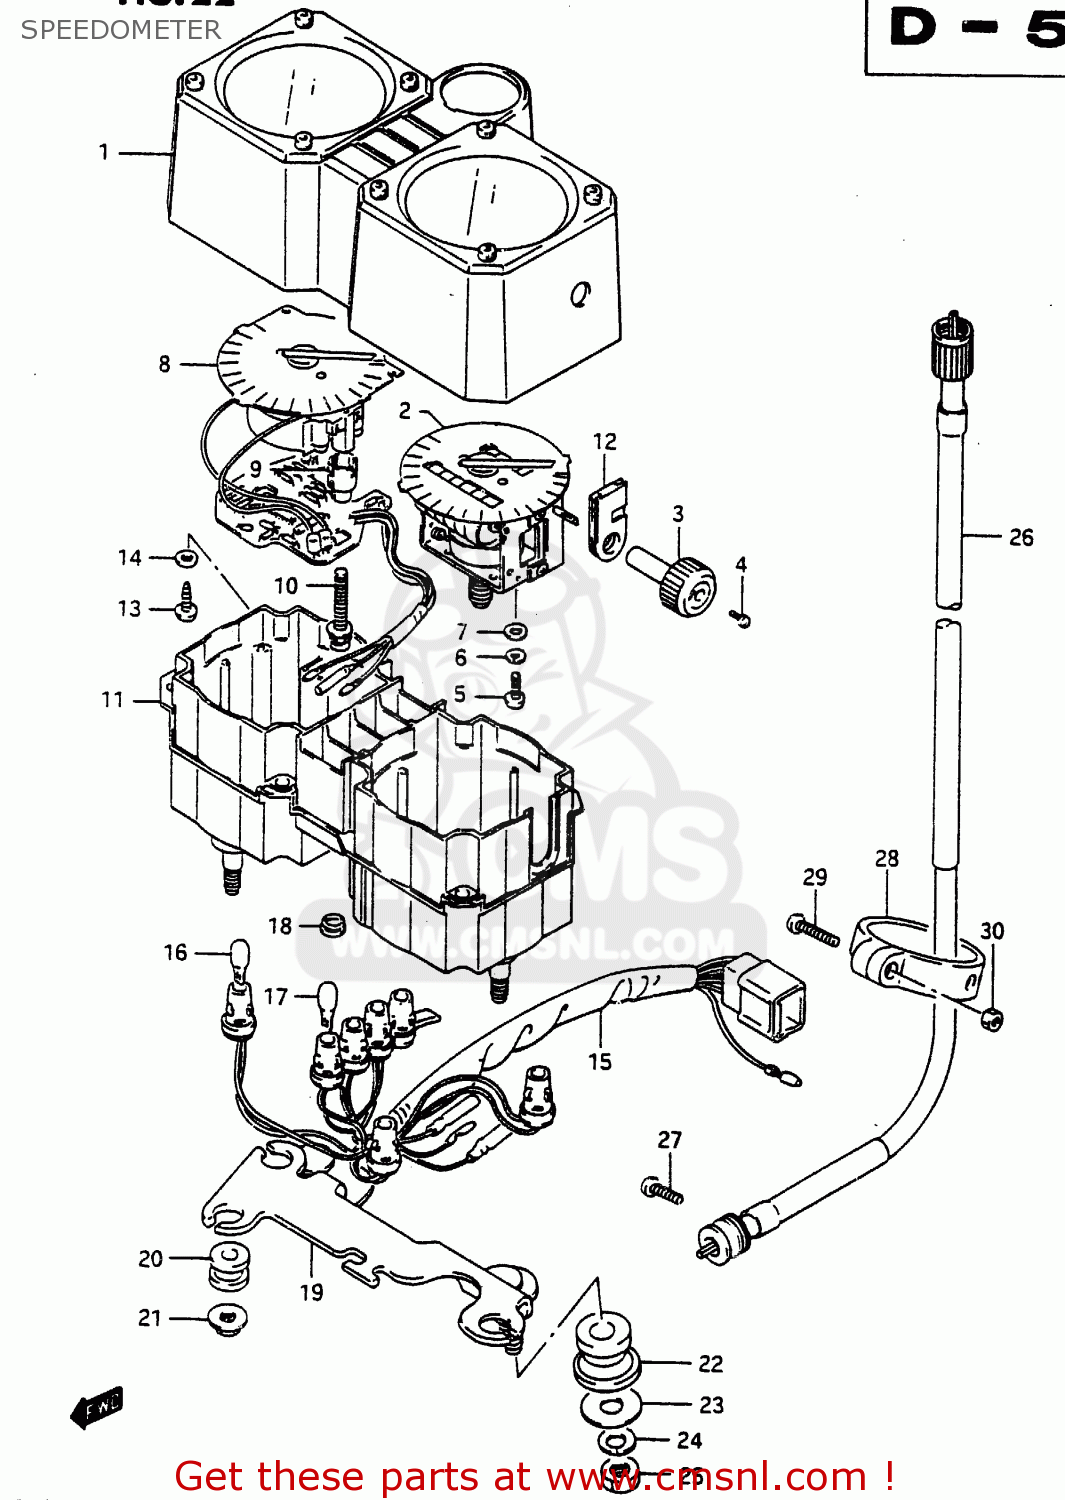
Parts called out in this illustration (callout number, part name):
1	HOOD,METER
2	SPEEDOMETER
3	KNOB,TRIP
4	SCREW,TRIP KNOB
5	SCREW
6	LOCK WASHER
7	WASHER 3.3X8X0
8	TACHOMETER
9	SPACER
10	SCREW
11	CASE,METER
12	CUSHION,METER
13	SCREW
14	LOCK WASHER
15	SOCKET,METER
16	BULB(12V1.7W,WB372,T7)
17	BULB(12V3W,WB371,T7)
18	CAP
19	BRACKET,METER
20	CUSHION,METER
21	NUT
22	CUSHION,METER BRACKET
23	WASHER (8.5X20X1.6)
24	WASHER,LOCK,8.
25	NUT ,8MM
26	CABLE ASSEMBLY,SPEEDOMETER
27	SCREW
28	CLAMP, METER CABLE
29	SCREW
30	NUT
